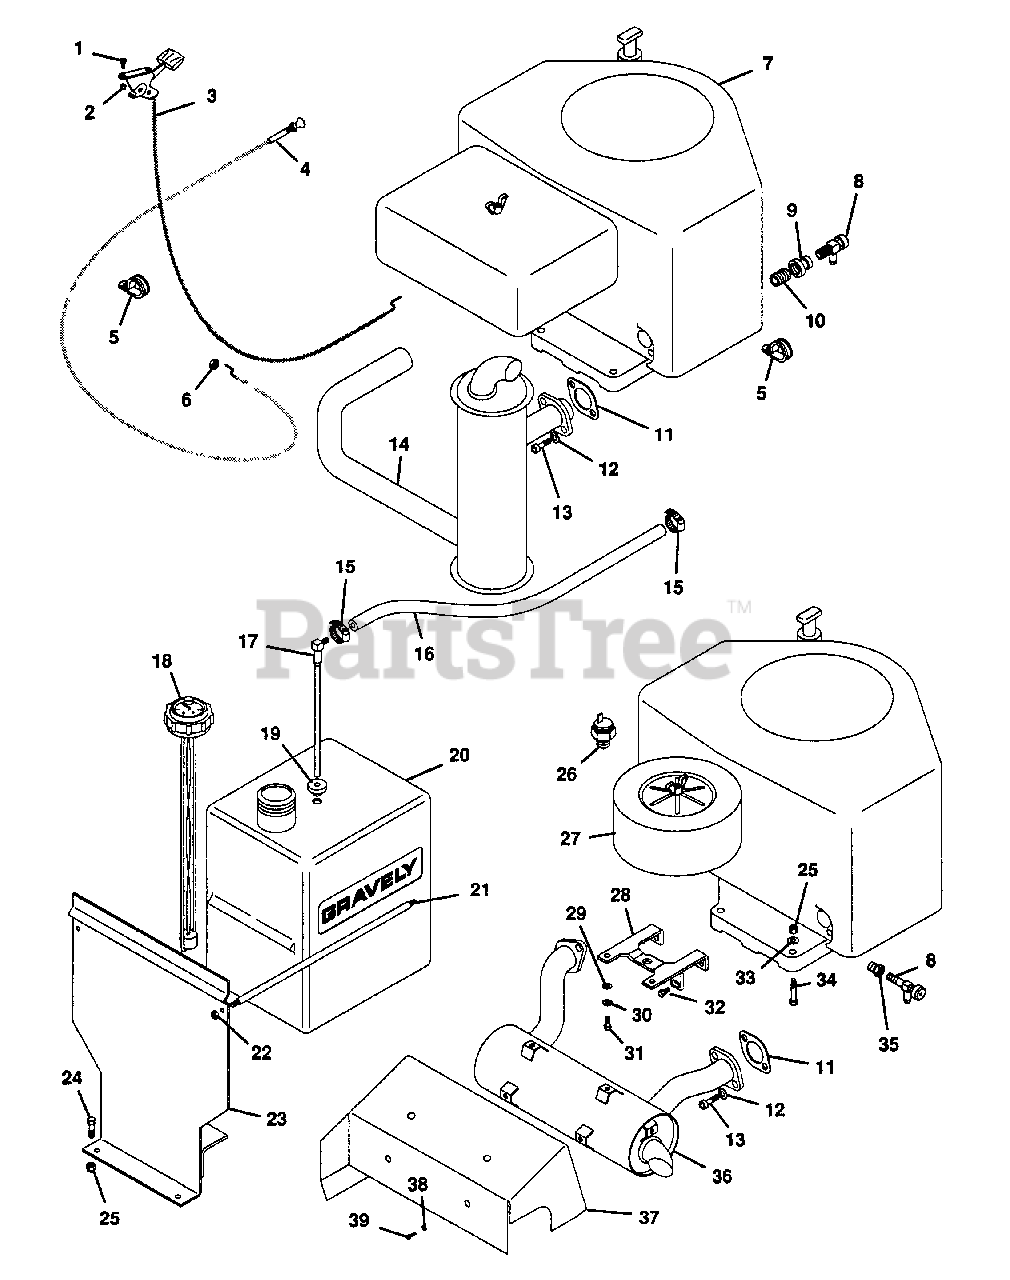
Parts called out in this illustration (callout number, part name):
1	SCREW, MACH. 10-24X.50 PHD
2	NUT, LOCK 10-24
3	LEVER, CONTROL
4	CONTROL, CHOKE
5	CLAMP, STEEL .625
6	NUT, JAM 3/8-24 HEX
7	ENGINE, 20 HP ONAN
8	COCK, OIL DRAIN
9	COUPLING, REDUCING 3/8X1/4
10	NIPPLE, 3/8 CLOSE
11	GASKET, EXHAUST
12	WASHER, LOCK 5/16 REG.
13	SCREW, CAP 5/16-18X.75 SHD
14	MUFFLER, ONAN
15	CLAMP, HOSE
16	LINE, FUEL
17	FITTING, TANK
18	GAUGE, FUEL
19	BUSHING
20	TANK, FUEL
21	ROD, TANK
22	NUT, LOCK 1/4-20
23	WELDMENT, TANK BRACKET
24	BOLT, HEX 5/16-18X.875
25	NUT, LOCK 5/16-18
26	SWITCH, PRESSURE
27	ENGINE, 18 HP KOHLER
27	ENGINE, 20 HP KOHLER
28	BRACKET, MUFFLER SUPPORT
29	WASHER, FLAT .281X.625X.065
30	WASHER, LOCK 1/4 REG.
31	BOLT, HEX 1/4-20X.75
32	SCREW, 1/4-20X.50 SELF TAPPING
33	WASHER, FLAT .344X.688X.065
34	BOLT, HEX 5/16-18X1.75
35	ADAPTOR, OIL DRAIN
36	MUFFLER, PRO MASTER 18-H
37	SHIELD, MUFFLER
38	WASHER, FLAT #10 .219X.5X.049
39	SCREW, 8-18X.50
